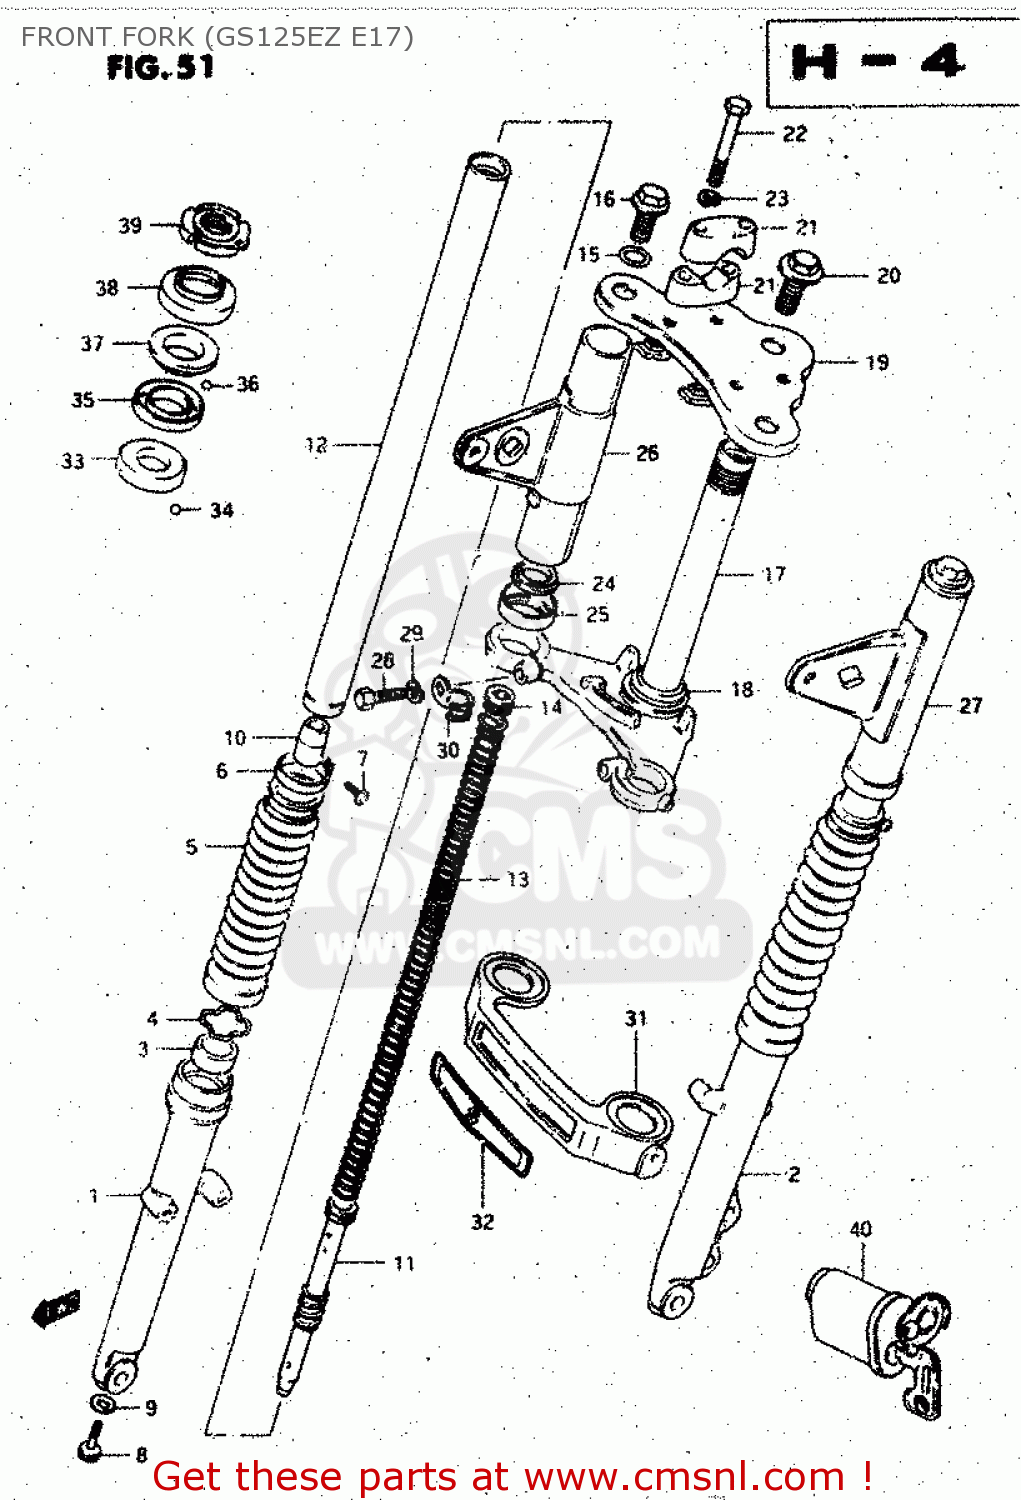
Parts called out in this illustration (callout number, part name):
1	TUBE,OUTER,R
2	TUBE,OUTER,L
3	OIL SEAL,FRONT FORK
4	RING,SNAP
5	BOOT
6	BAND,BOOT
7	SCREW
8	BOLT,FORK CYLINDER(10X25)
9	GASKET (NAS)
10	PIECE,OIL LOCK
11	FRONT FORK DAMPER TUBE
12	TUBE, INNER
13	SPRING
14	NUT
15	O RING
16	CAP
17	STEM, STEERING
18	RACE,STEERING OUTER LWR
19	HEAD,STEERING STEM
20	BOLT
21	HOLDER,HANDLE UPR
22	BOLT
23	LOCK WASHER
24	CUSHION
25	GUIDE,BRACKET
26	BRACKET, HEADLAMP RH
27	BRACKET, HEADLAMP LH
28	BOLT,FR FORK LWR(12X33)
29	WASHER,LOCK 12
30	CLIP
31	COVER, FRONT FORK
32	EMBLEM,FR FORK COVER
33	LACE,STEERING INNER LWR
34	BALL
35	RACE,STEERING INNER UPR
36	BALL
37	RACE,STEERING OUTER UPR
38	DUST SEAL,STEERING UPR
39	NUT,STEERING STEM(25X44X10)
40	LOCK ASSY, STEERING (NEIMAN TYPE EXECUTE
